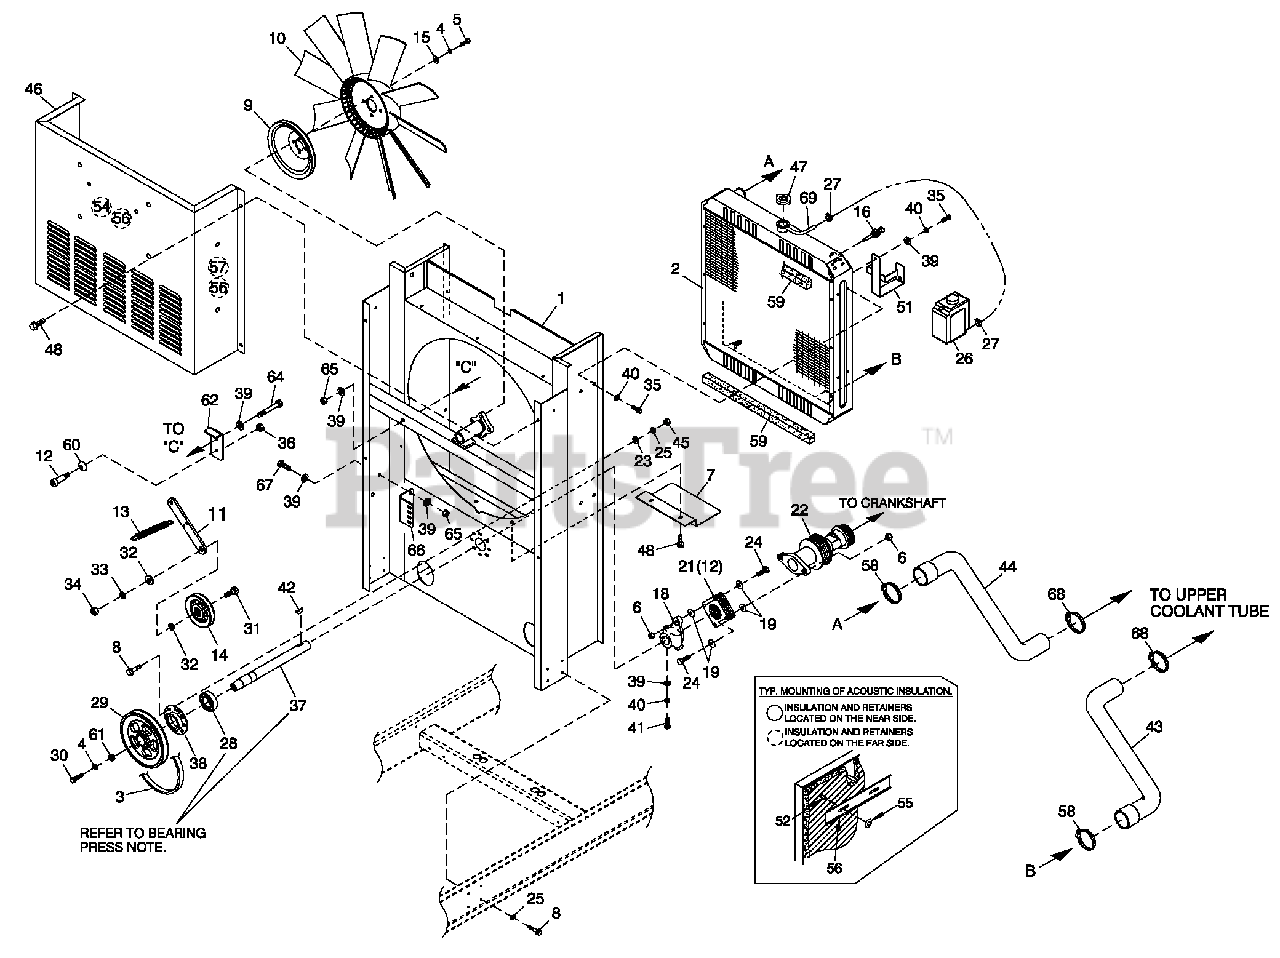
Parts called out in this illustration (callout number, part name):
1	WELDMENT RADIATOR SUPPORT C4
2	RADIATOR 598 X 568 X 49 CPL LH
3	V- BELT 31/64"X 57-3/8"
4	WASHER LOCK M10
5	SCREW HHC M10-1.5X30G10.9
6	NUT HEX LOCK 5/16-24 NY INS
7	SHIELD RADIATOR C4
8	SCREW HHFC M6-1.0X20G8.8
9	PULLEY FAN V-GROOVE 9"
10	FAN COOL 22"DIA 10 BLADE LH
11	FLATTENSIONERARM
12	SHOULDER BOLT 3/8 X 1/2"
13	SPRING TENSION CPL
14	PULLEY V- BELT 4"FLANGED
15	WASHER FLAT 3/8-M10 ZINC
16	PRO BE COOLANT LEVEL 3/8 NPTF
18	HU B FLEX PLATE
19	WASHER FLEX (THIN)
21	DISK FLEX
22	ADAPTER CRANKSHAFT
23	WASHER FLAT 1/4-M6 ZINC
24	SCREW HHC 5/16-24X1.124
25	WASHER LOCK M6-1/4
26	TANK COOLANT RECOVERY
27	CLAMP HOSE BAND 1/4
28	BEARING #6205 2NSE C3 E SRI2 S
29	PULLEY 5.5"DIA MACHINED
30	SCREW HHCM10-1.5X30 G8.8
31	SCREW HHC 1/2-13 X 2"G8
32	WASHER FLAT 1/2 ZINC
33	WASHER LOCK 1/2
34	NUT HEX 1/2-13 STEEL
35	SCREW HHFC M8-1.25 X 20 W/M6
36	NUT HEX LOCK 5/16-18 NY INS SS
37	SHAFT FAN DRIVE C4
38	RETAINER BEARING
39	WASHER FLAT 5/16-M8 ZINC
40	WASHER LOCK M8-5/16
41	SCREW HHC M8-1.2 5X 3 5 G8.8
42	KEY WOODRUFF 4X 1 9D
43	HOSE RADIATOR CPL C4
44	HOSE UPPER RAD FRT C4
45	NUT HEX M6X 1.0 G8YEL CHR
46	INNER DISCHARGE DUCT, C4
47	CAP RADIATOR 13 PSI
48	SCREW THF M6-1 X 16 N WA Z/JS
51	BRACKET COOLANT TANK
52	INSULATION RETAINMENT HANGER
54	INSULATION FRONT INNER DUCT
55	WASHER SELF LOCKING DOME
56	RETAINER INSULATION (450)
57	INSULATION INNER DUCT
58	CLAMP HOSE #28 1.32-2.25
59	TAPE FOAM 1 X 1 (26.75" LG)
60	WASHER BELLEVILLE .75X.38X.028
61	SPACER .5 X 1.5 X .25 STL/ZINC
62	TENSIONERARM SUPPORT BENT 90
64	SCREW HHC M8-1.2 5X 7 5 C8.8
65	NUT HEX LOCK M8-1.25 NY INS
66	BRACKET TENSIONER SPRING
67	SCREW HHC M8-1.2 5X 2 0 C8.8
68	CLAMP HOSE #24 B1.06-2.00
69	HOSE 9/32 ID (27"LG)
